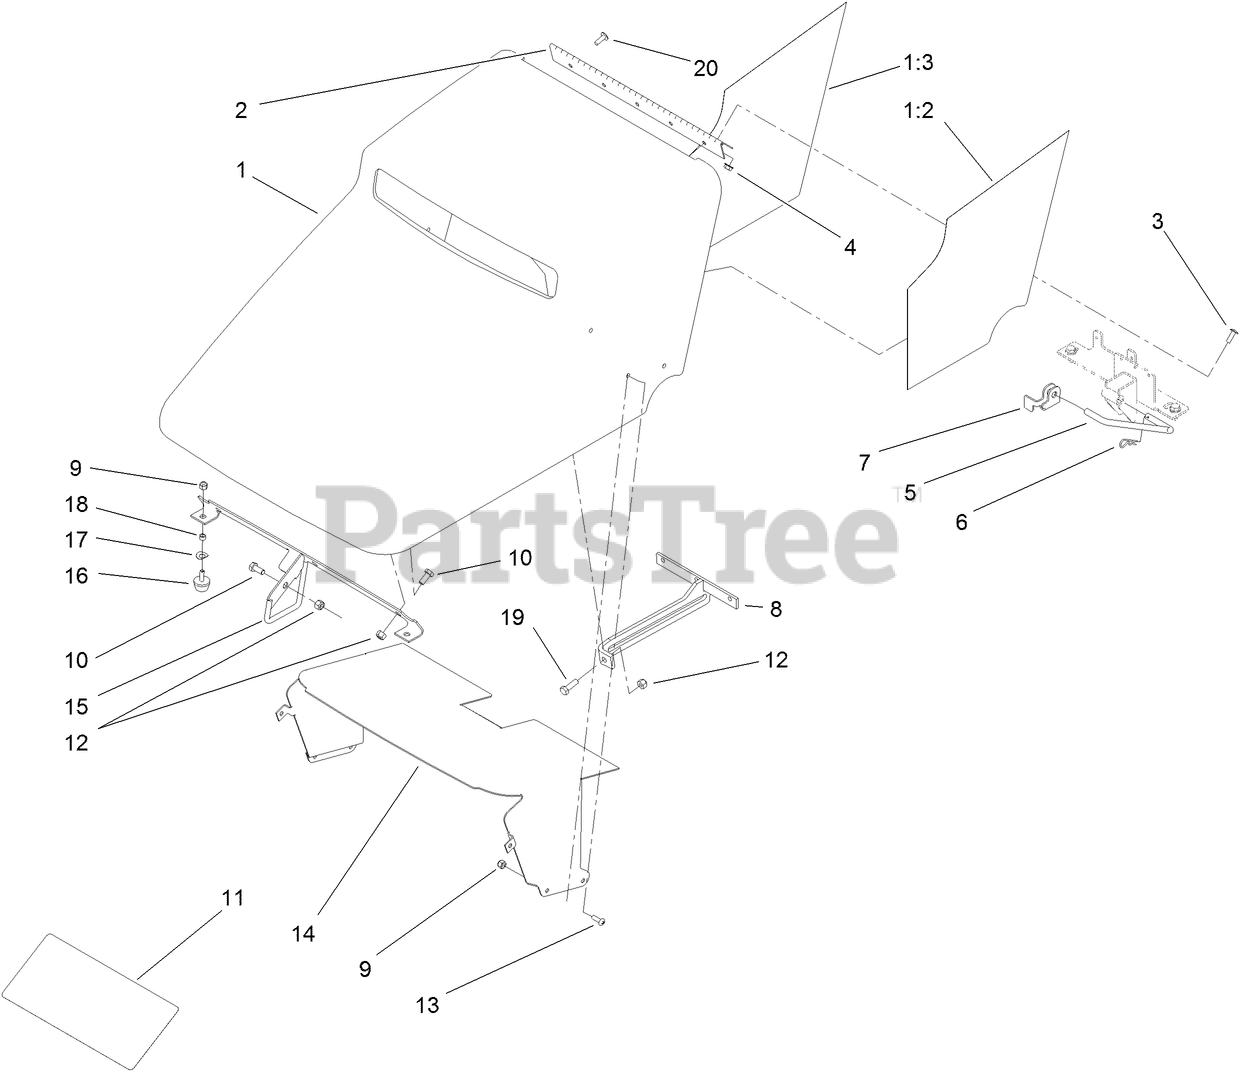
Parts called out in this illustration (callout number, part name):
1	HOOD ASM
1:2	FOILTAPE-LH
1:3	FOILTAPE-RH
2	HINGE-HOOD
3	SCREW-HEAD, TRUSS
4	NUT-HF
5	ROD-SUPPORT, HOOD
6	PIN-COTTER
7	BRACKET-LATCH, LOCKING
8	PROP ROD BRACKET ASM
9	NUT-LOCK, NI
10	SCREW-HH
11	DECAL-SERVICE
12	NUT-LOCK, NI
13	SCREW-PRH
14	BAFFLE-HOOD
15	ROD LATCH ASM
16	BUMPER
17	WASHER-SPRING
18	SPACER
19	SCREW-HH
20	SCREW-HH
